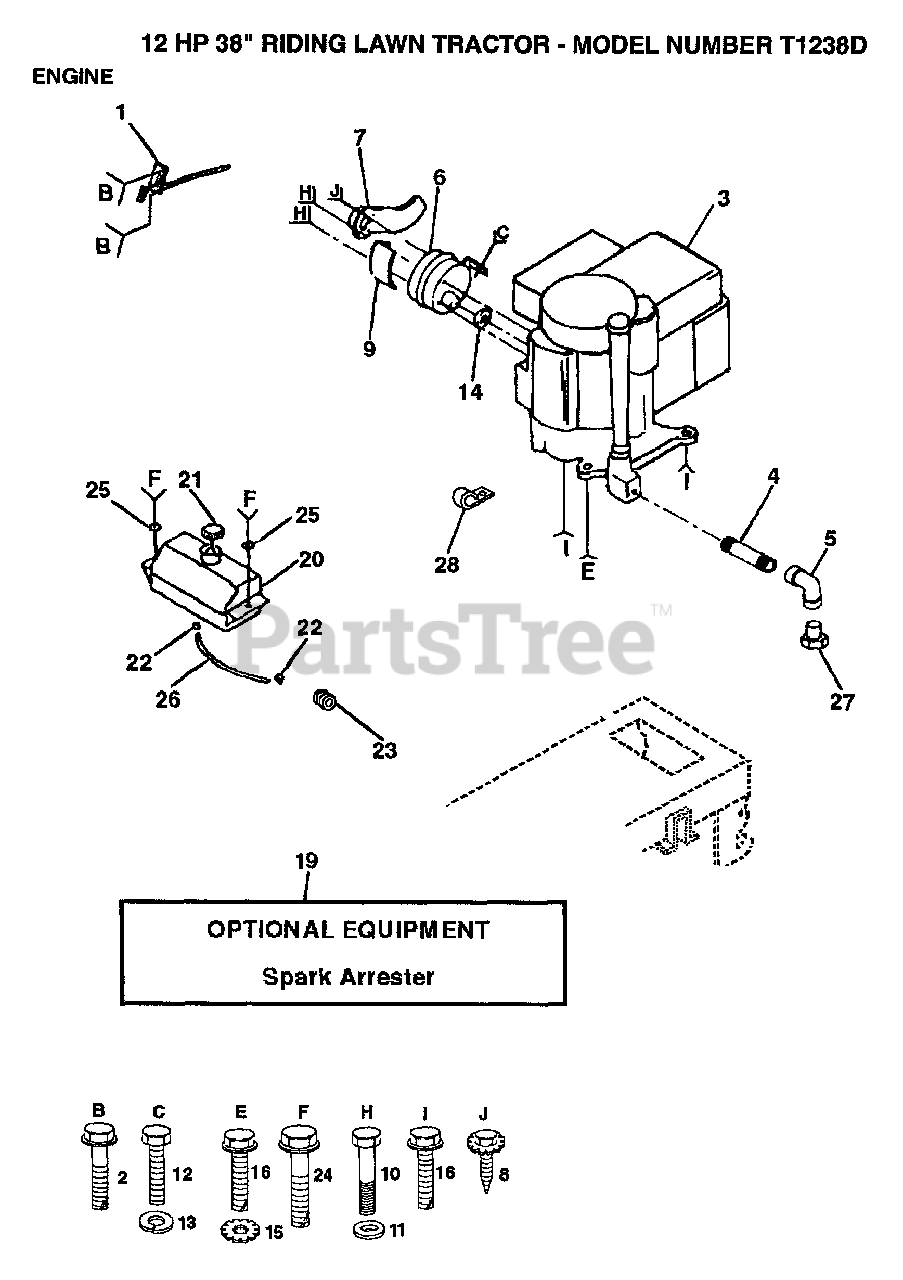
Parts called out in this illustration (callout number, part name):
2	SCREW LT
4	PIPE NIPPLE
5	ELBOW
6	MUFFLER LTV
7	DEFLECTOR MUFFLER
9	SHIELD HEAT LTV
10	"BOLT,HEX"
11	WASHER T
12	BOLT
13	LOCKWASHER
15	LOCKWASHER
16	SCREW
19	SPARK ARREST KIT
20	TANK.FUEL.LT.
22	HOSE CLAMP
24	SCREW
25	WASHER GT
26	FUEL LINE T
28	CLIP T
